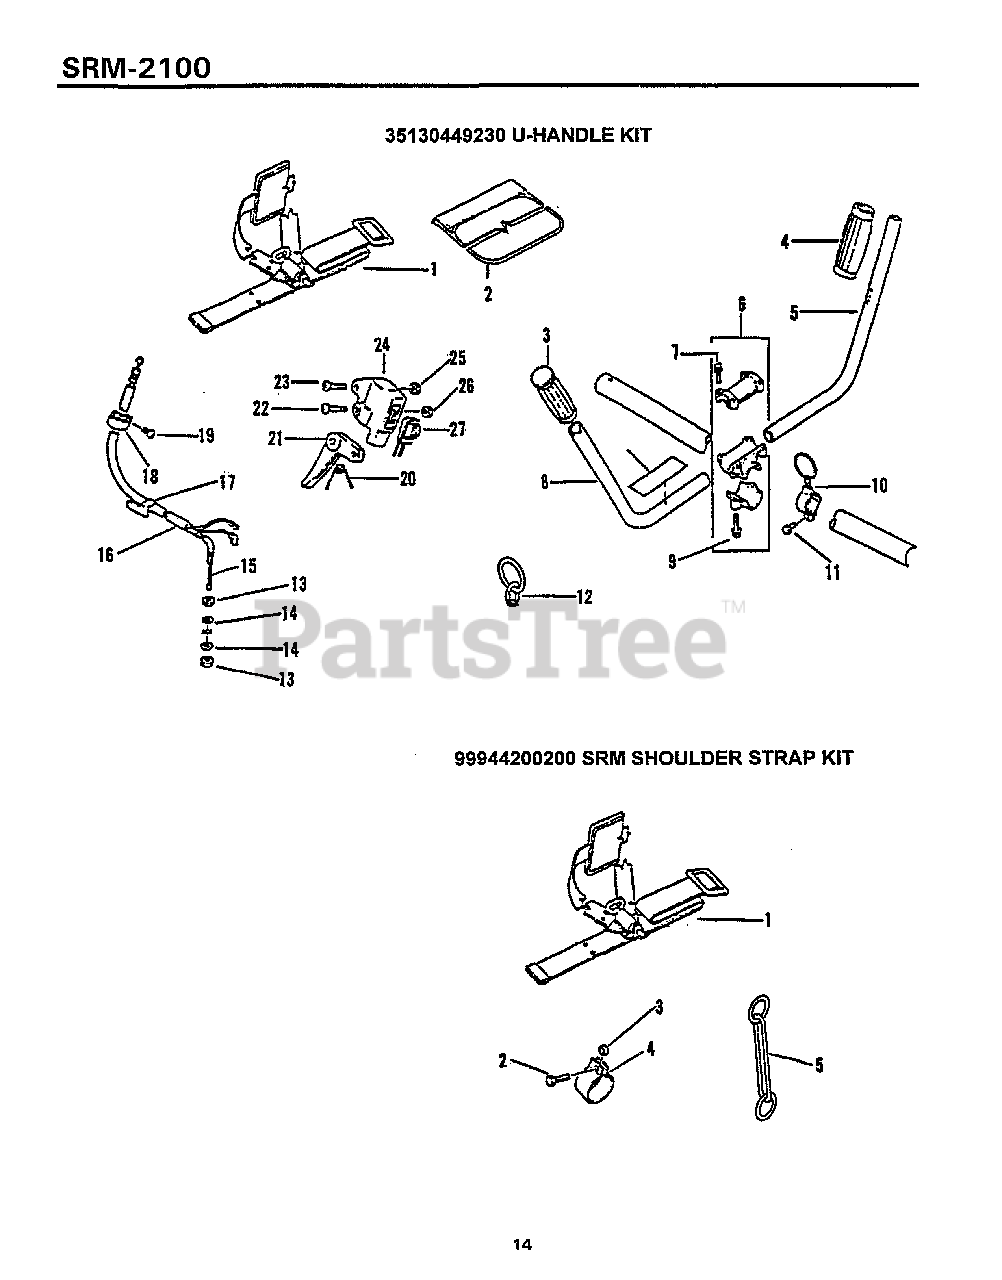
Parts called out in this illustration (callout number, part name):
1	SHOULDER STRAP ASSY
2	PAD, HIP
2	BOLT 5×18
3	GRIP, HANDLE
3	SPACER, GUARD
5	HOOK
6	HANDLE BRACKET KIT
7	BOLT - 5×25
8	HANDLE, LEFT
9	BOLT - 6×30
10	HOOK
11	BOLT 5×12
12	RING, HARNESS
14	WASHER 6.5×11.5×0.8
15	CABLE, THROTTLE
16	TUBE
19	SCREW 5×10
21	CONTROL, THROTTLE
22	SCREW 5×25
24	BRACKET, THROTTLE
25	NUT, LOCK M5
26	NUT M5
27	IGNITION SWITCH ASSY
